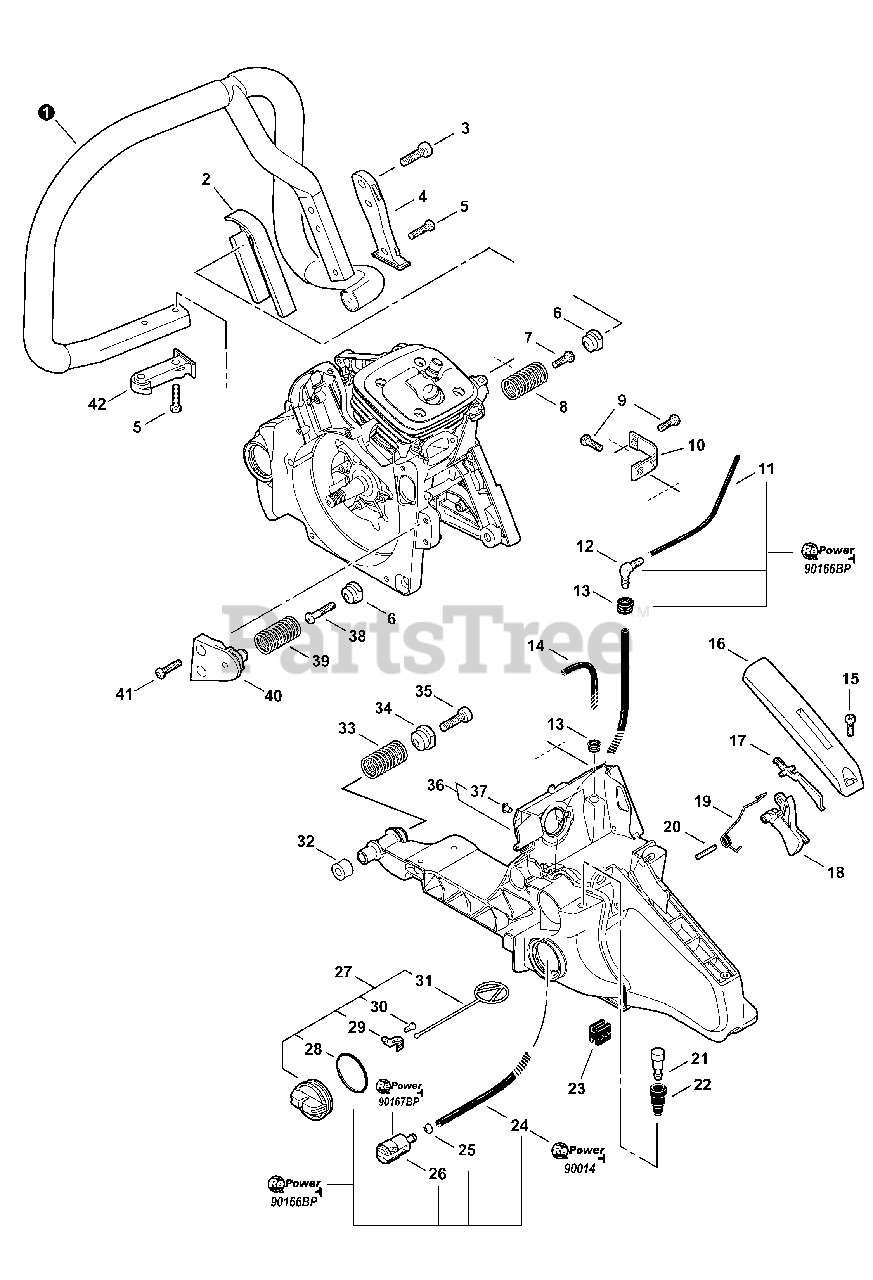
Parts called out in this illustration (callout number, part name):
1	HANDLE, FRONT
2	HOLDER,SPRING
3	BOLT, TORX 6
4	BRACKET,HANDLE
5	BOLT, TORX 5
6	HOLDER,SPRING
7	BOLT, TORX 5
8	SPRING,COMPRESSION
9	BOLT, TORX 5
10	STOPPER
11	PIPE, FUEL 3×6×135L
12	JOINT,PIPE
13	GROMMET
14	PIPE, IMPULSE 3×6×160
15	BOLT, TORX 4
16	LID,HANDLE
17	LOCKOUT, T. CONTROL
18	CONTROL, THROTTLE
19	SPRING,TORSION
20	PIN, SPRING 4×25SUS
21	VENT ASSEMBLY, FUEL
22	COVER,VENT
24	PIPE, FUEL 3×5×120
26	STRAINER, FUEL
27	CAP,FUEL ASSY
28	O-RING 29
29	RETAINER, LINK
30	SCREW 3×8
31	LINK
32	CUSHION
33	SPRING,COMPRESSION
34	HOLDER,SPRING
35	BOLT, TORX 6
36	HANDLE, REAR
38	BOLT, TORX 5
39	SPRING,COMPRESSION
40	HOLDER,SPRING
41	BOLT, TORX 5
42	BRACKET,HANDLE
